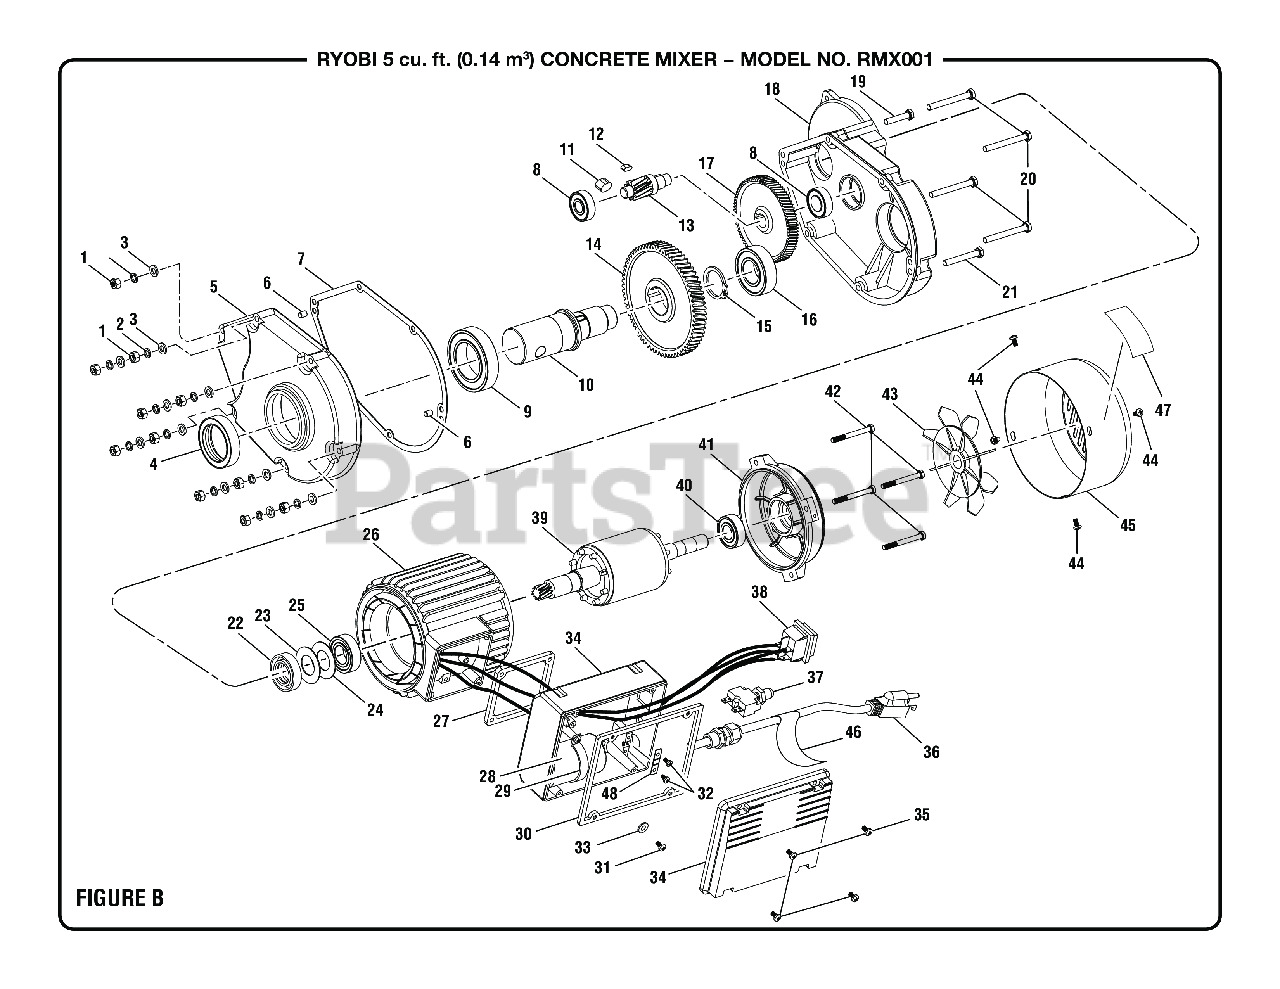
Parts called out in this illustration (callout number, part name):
1	Hex Nut (M6)
2	Lock Washer (M6)
3	Washer (M6)
4	Seal (40 mm)
5	Gear Case (Front Cover)
6	Locking Pin (M6 x 10 mm)
7	Gearbox Gasket
8	Gearbox Ball Bearing (6201z)
9	Ball Bearing (6008)
10	Drive Shaft
11	Large Locking Key (8 x 15 mm)
12	Small Locking Key (5 x 5 x 12 mm)
13	Pinion (Z9)
15	Retaining Ring B (30 mm)
16	Ball Bearing (6205)
18	Gear Case (Back Cover)
19	Screw (M6 x 25 mm, Pan Hd.)
20	Screw (M6 x 65 mm)
21	Bolt (M6 x 42 mm)
22	Motor Seal (42 x 20 x 7 mm)
23	Spacer Washer A (42 mm)
24	Stop Ring (30 MM)
25	Motor Bearing (6004z)
27	Motor Gasket
28	Condenser (30UF)
30	Gasket (Panel Box)
31	Ground Screw (M4 x 10 mm)
32	Screw (M4 x 10 mm)
33	Washer (4 mm)
34	Panel Box Assembly
35	Screw (M4 x 22 mm)
36	Power Cord (Inc. Key No. 46)
37	Overload Protector
38	On/Off Switch
40	Ball Bearing (6202z)
41	Bell Housing
42	Bolt (M5 x 138 mm)
44	Screw (M4 x 10 mm)
45	Fan Cover (Inc. Key No. 47)
46	Cord Wrap Label
47	Motor Specifications Label
48	Strain Relief Pressure Plate
